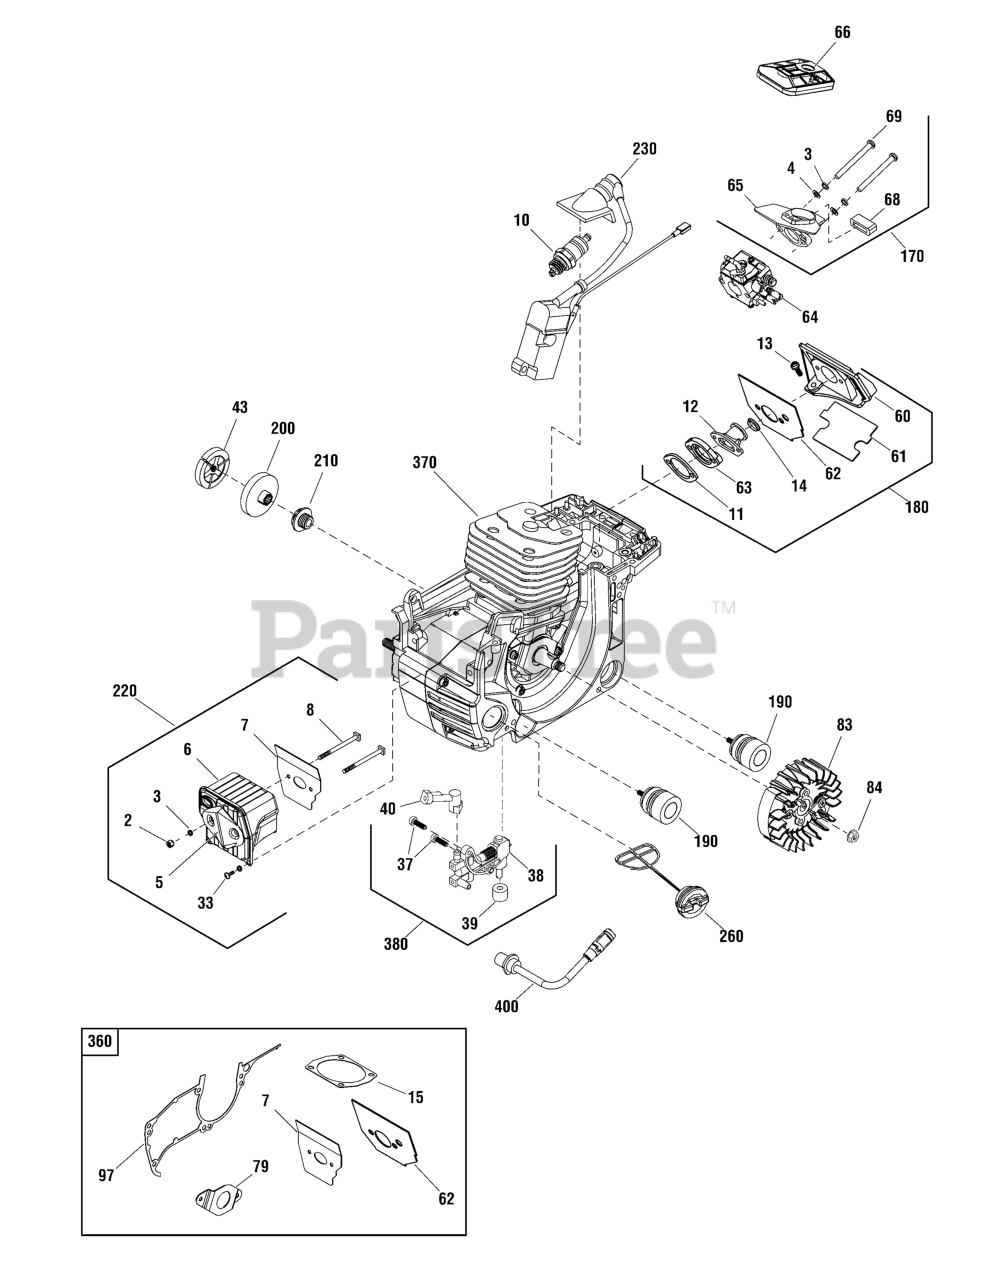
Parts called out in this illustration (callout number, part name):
5	PLATE, Muffler Cover
6	MUFFLER
7	GASKET, Muffler
8	SCREW, Muffler
10	SPARK PLUG, Champion
11	GASKET, Air Intake
12	TUBE, Air Intake
14	RETAINER RING
15	SEALING PLATE, Cylinder
38	OIL PUMP
39	SPONGE TRANSITION COIL
40	NOZZLE
43	CLUTCH
60	TUBE SUPPORT, Air Intake
61	TIE PLATE
62	SEALING PLATE, Air Intake
63	TUBE FLANGE, Air Intake
64	CARBURETOR, Walboro WT893A
65	SOCKET, Air Intake
66	AIR FILTER
68	CUSHION, Air Intake Socket
79	OIL SHIELD
83	FLYWHEEL
84	NUT, M8
97	SEALING PLATE, Case Body
170	AIR FILTER MOUNT ASSEMBLY
180	AIR INTAKE ASSEMBLY
190	SHOCK SEAT ASSEMBLY
200	CLUTCH CUP ASSEMBLY
210	DRIVESPROCKET ASSEMBLY
220	MUFFLER
230	IGNITION UNIT
260	CAP, Oil
360	KIT, Gasket
370	SHORT ENGINE, 45cc
380	OIL PUMP ASSEMBLY
400	OIL FILTER
